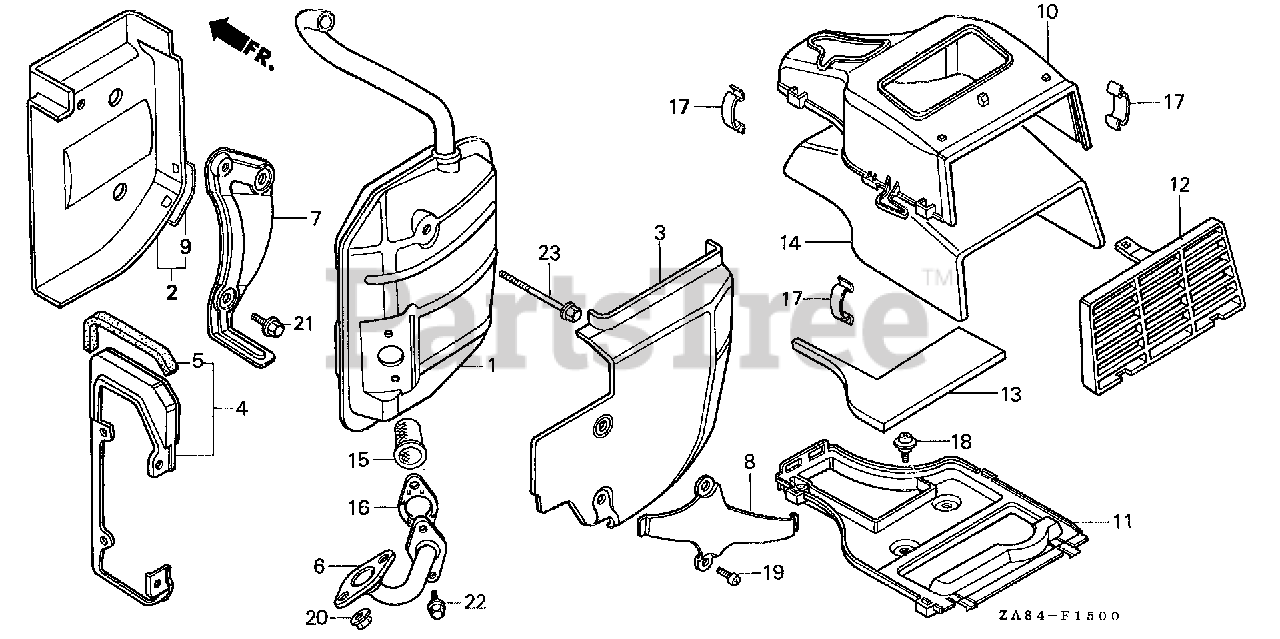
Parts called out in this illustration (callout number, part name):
2	SEPARATOR ASSY. (INNER)
3	SEPARATOR, GLASS WOOL (OUTER)
4	BRACKET ASSY., GLASS WOOL
5	SEAL, GLASS WOOL BRACKET
6	PIPE, EX.
7	BRACKET, MUFFLER
8	PLATE, SEPARATOR PUSHING (OUTER)
9	PLATE, SEPARATOR (OUTER)
10	CHAMBER, EXPAND (UPPER)
11	CHAMBER, EXPAND (LOWER)
12	GRID, EXPAND CHAMBER
13	WOOL, EXPAND CHAMBER GLASS (LOWER)
14	WOOL, EXPAND CHAMBER GLASS (UPPER)
15	ARRESTER, SPARK
16	GASKET, MUFFLER
16	GASKET, MUFFLER (NOT AVAILABLE)
17	CLAMP, CASE
18	SCREW, PAN (5X5)
19	SCREW, PAN (5X16)
20	NUT, FLANGE (6MM)
21	BOLT, FLANGE (6X12)
22	BOLT, FLANGE (6X16)
23	BOLT, FLANGE (6X60)
